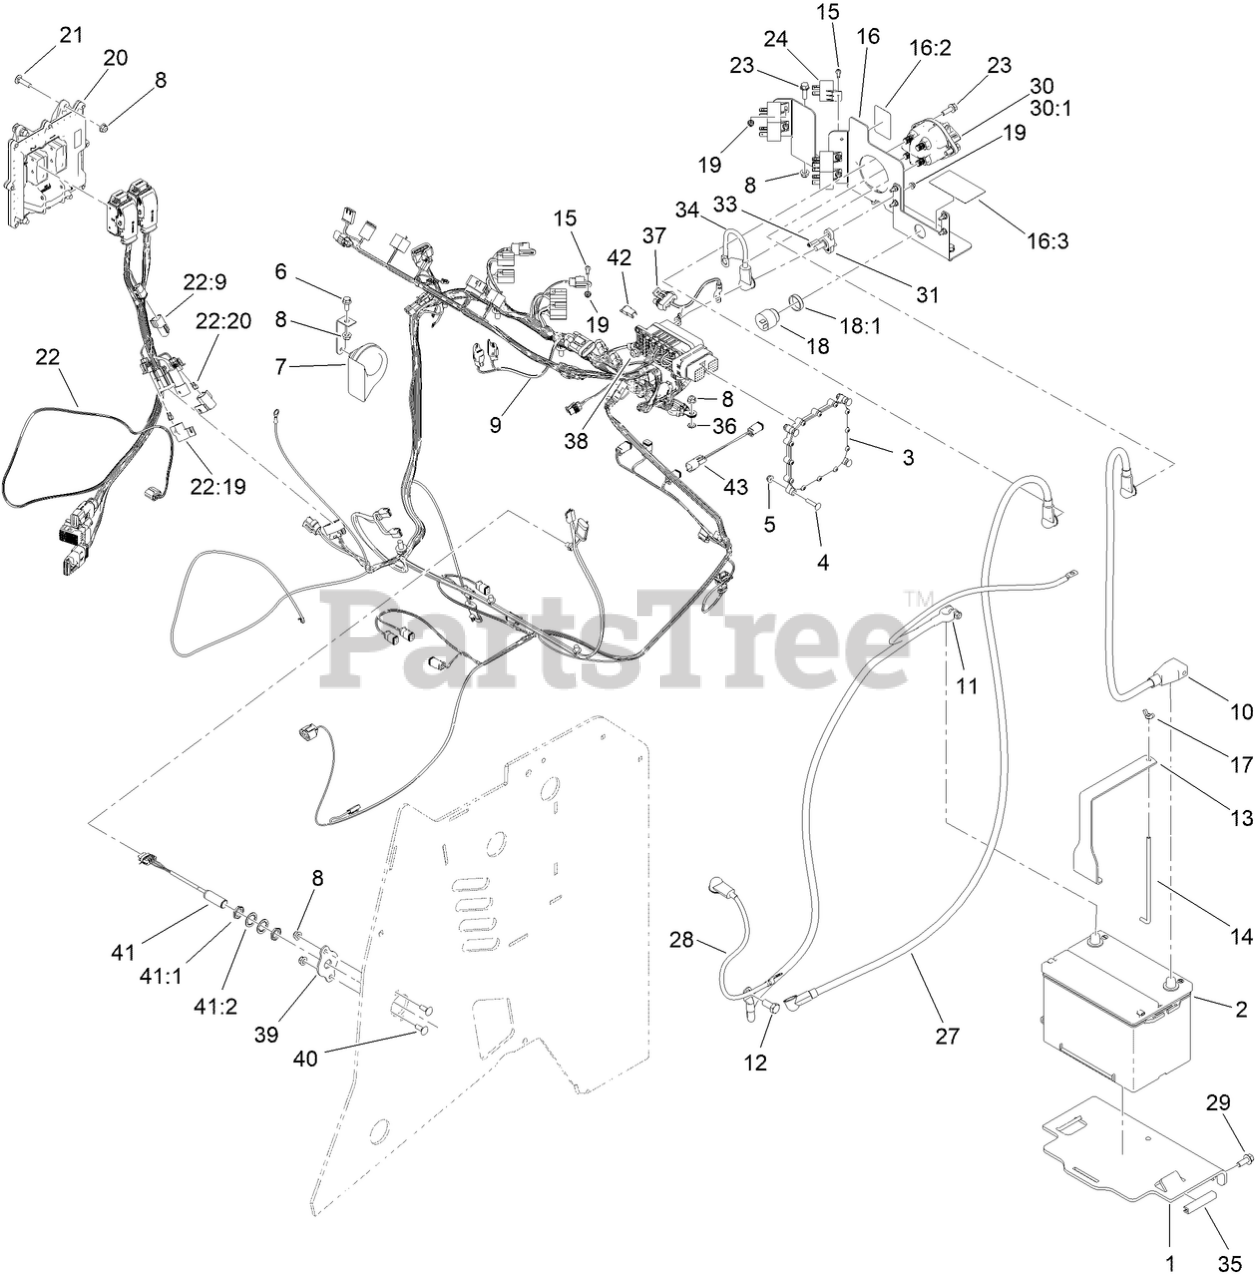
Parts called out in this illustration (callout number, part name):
1	BRACKET-BATTERY
2	BATTERY
3	CONTROLLER
4	SCREW-CARR
5	NUT-HF
6	SCREW-HHF
7	Horn And Bracket Assembly (Inc. Ref.# 44 45)
8	NUT-HF, NI
9	HARNESS-WIRE,MAIN,
10	CABLE-BATTERY, POSITIVE
11	CABLE-BATTERY, NEGATIVE
12	SCREW-HH
13	PLATE-HOLD, BATTERY
14	ROD-HOLD DOWN, BATTERY
15	SCREW-HWH
16	BRACKET-COMPONENTS, ELECTRICAL
16:2	DECAL-BATTERY POWER
16:3	DECAL - FUSES
17	NUT-WING
18	AUDIO ALARM ASM
18:1	NUT-PLASTIC, KNURLED
19	NUT-HF
20	ECU-ENGINE
21	SCREW-CARR
22	HARNESS-WIRE,
22:9	RESISTOR-120 OHM
22:19	COVER-FUSE, SINGLE
22:20	FUSE-MINI BLADE, 5 AMP
23	SCREW-HHF
24	RELAY
27	CABLE-BATTERY, POSITIVE
28	CABLE-BATTERY, POSITIVE
29	SCREW-HHF
30	SWITCH-DISCONNECT
30:1	NUT-HF
31	BLOCK-JUNCTION
33	SCREW-HSH
34	CABLE-BATTERY, POSITIVE
36	WASHER-LOCK
37	HARNESS-WIRE, FUSIBLE LINK
38	NUT-HF, NI
39	PLATE-MOUNT, SENSOR
40	SCREW-CARR
41	PROXIMITY SWITCH ASM
41:1	NUT-HEX
41:2	WASHER-LOCK, INTERNAL TOOTH
42	HARNESS-WIRE, FUSIBLE LINK
43	HARNESS-JUMPER
